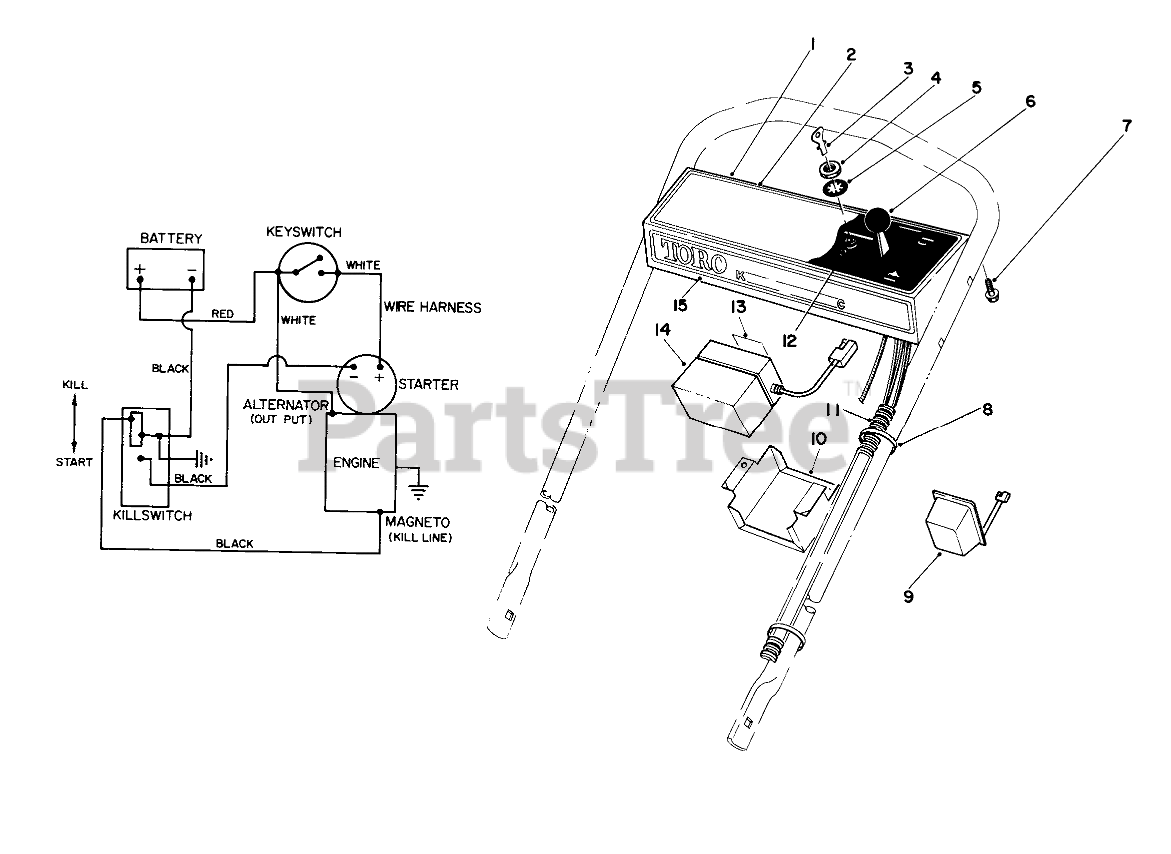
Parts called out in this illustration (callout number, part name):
1	Control Panel (Incl. Ref. #2)
2	Decal-Instructions
3	Key
4	NUT-HH
5	WASHER-TOOTH, INTERNAL
6	SERVICE THROTTLE CONTRO
7	SCREW-HWHTF
8	TIE-CABLE
9	Charger
10	Retainer-Battery
11	WIRE HARNESS
12	Switch-Starter (Incl. Ref. #4 & 5)
13	Decal
14	Battery Assembly
15	Decal-Toro
